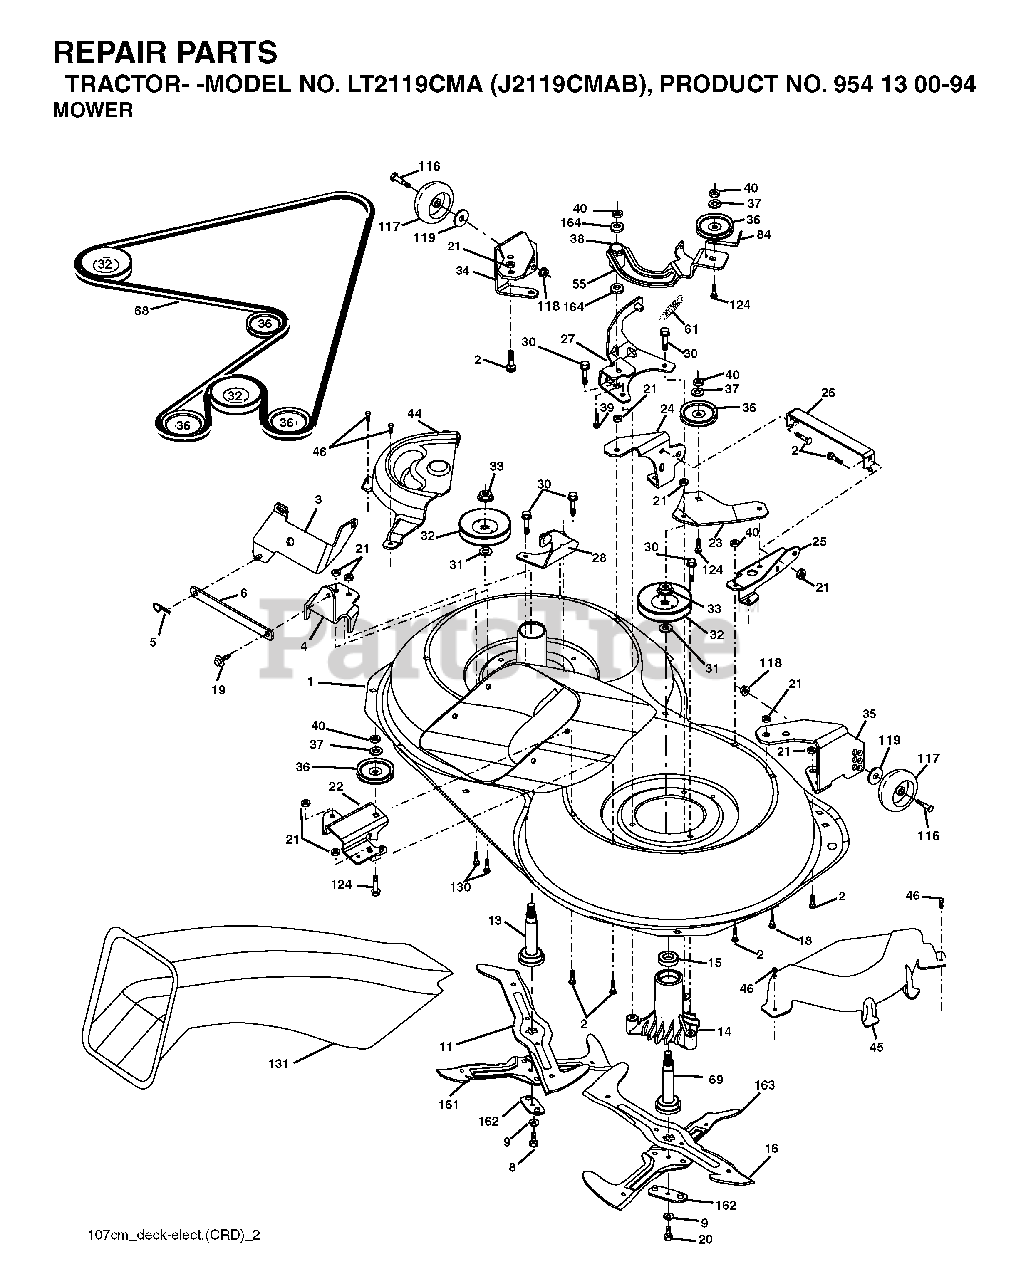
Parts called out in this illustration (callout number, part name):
2	BOLT
3	BRACKET
5	RETAINER-SPRNG RB
6	BAR SWAY
9	LOCKWASHER
11	BLADE.3N1.LH.CRD
13	SHAFT ASM VENT
14	HSG MANDREL
16	BLADE.3N1.RH.CRD
19	BOLT SHD 5/16-18
21	LOCKNUT
22	BRACKET
23	BRACKET
26	BRACE
27	BRACKET
30	SCREW, WASHER HEAD
31	WASHER
33	NUT, FLG TOPLOCK 9/16"
36	PULLEY.IDLER.4.25
40	LOCKNUT
45	MANDREL COVER
46	SCREW.1/4-20X5/8
55	ARM IDLER
68	HEX-BELT 107 MOWER
69	SHAFT.ASM.W/LWR.BRG.RH.THREAD
84	KEEPER, BELT IDLER
116	SHOULDER BOLT
117	WHEEL GAGE DONUT
118	LOCKNUT
119	WASHER
124	BOLT.3/8-16X1.50
131	CHUTE BAGGER
164	BRNG T
